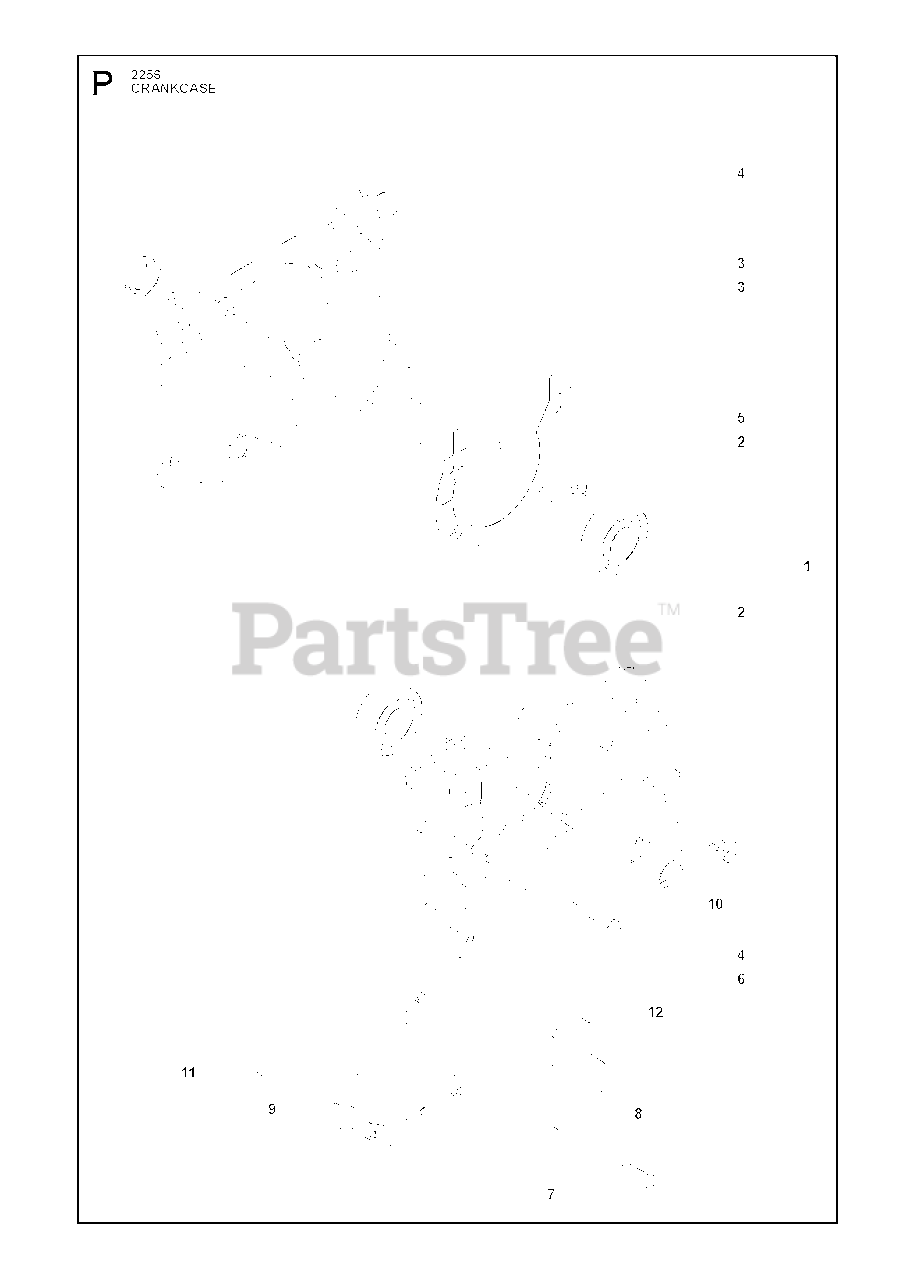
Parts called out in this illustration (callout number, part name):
1	CRANKCASE
2	BALL BEARING
3	PIN 5X14
4	SEALING RING
5	CRANKCASE GASKET
6	SCREW MC6S 5X25
9	CABLE HOLDER
11	SHORT CIRCUIT CABLE
